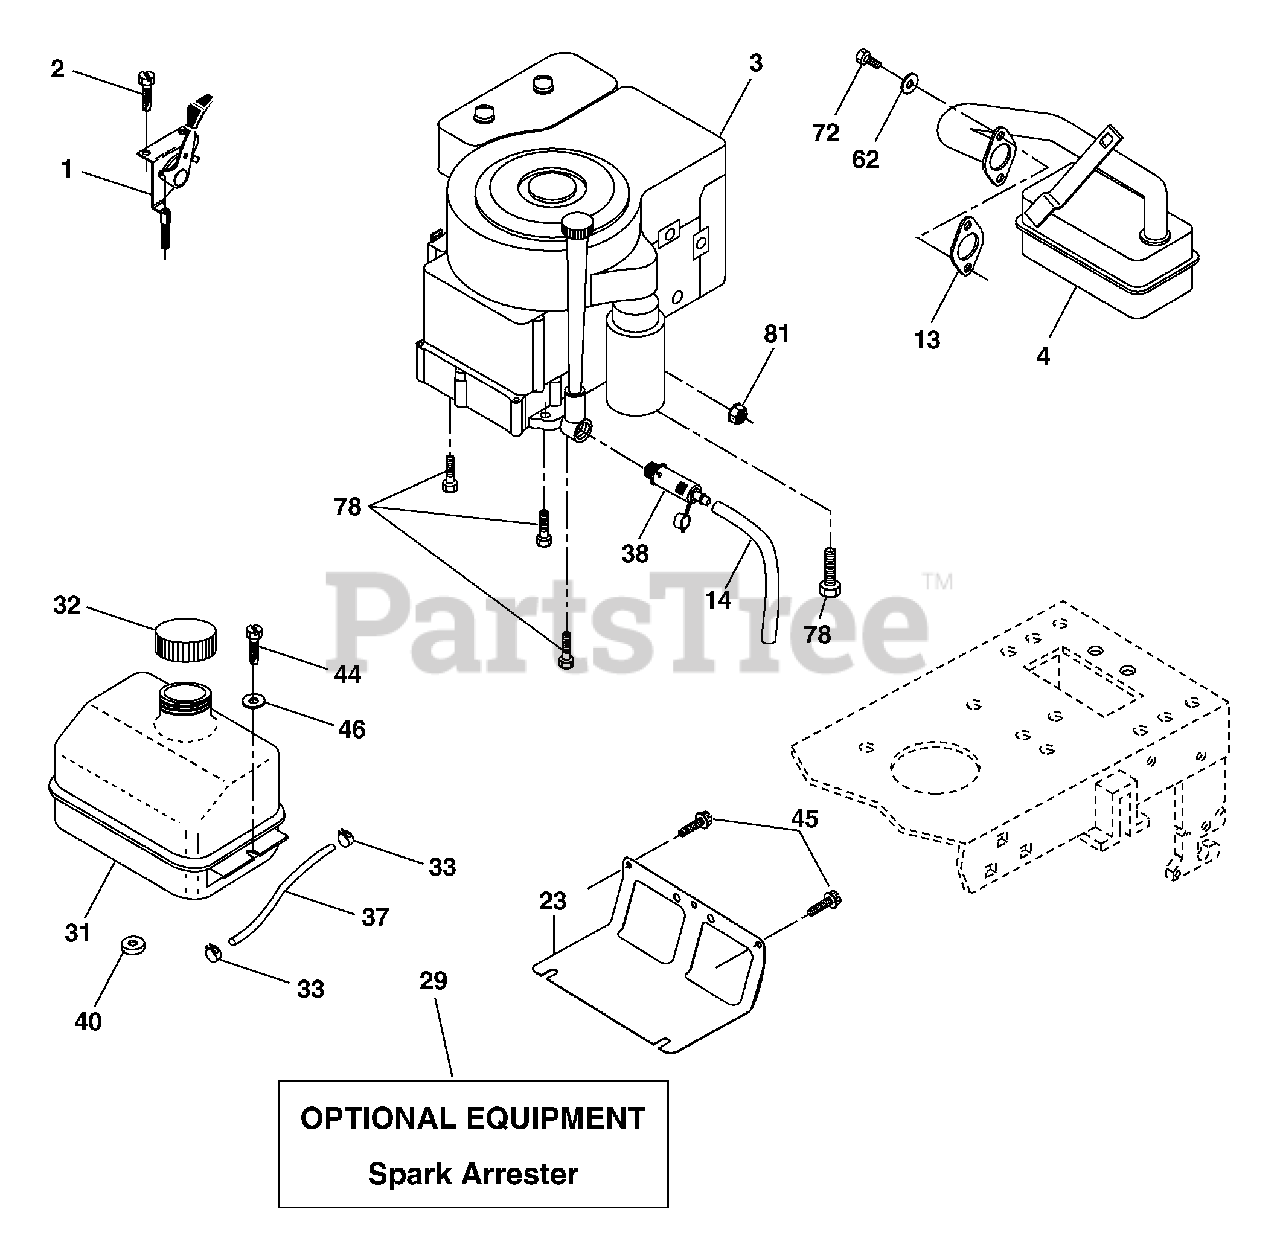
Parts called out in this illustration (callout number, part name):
1	Control Th/ch Flag
2	Screw Hex Thd Cut 1/4-20 x 1/2
4	Muffl er Exhaust B&S
13	Gasket Eng 1 313 Id Tin Plated
14	Tube Drain Oil Easy
23	Shield BRN/DBR Guard
29	Kit Spark Arrestor (Flat Scrn)
31	Tank Fuel Front
32	Cap Asm Fuel
33	Clamp Hose
37	Line Fuel 20"
38	Plug Drain Oil
40	Bushing Snap Nyl Blk Fuel Line
44	Screw Thdrol 1/4-20 x 3/4
45	Screw Hex Wsh Thdrol 3/8-16
46	Washer 9/32 x 7/8 x 16 Ga.
62	Washer Split
72	Screw Socket Head 5/16-18 x 3/4
78	Screw 3/8-16 x 1-1/4
81	Nut Keps Hex 1/4-20 unc
